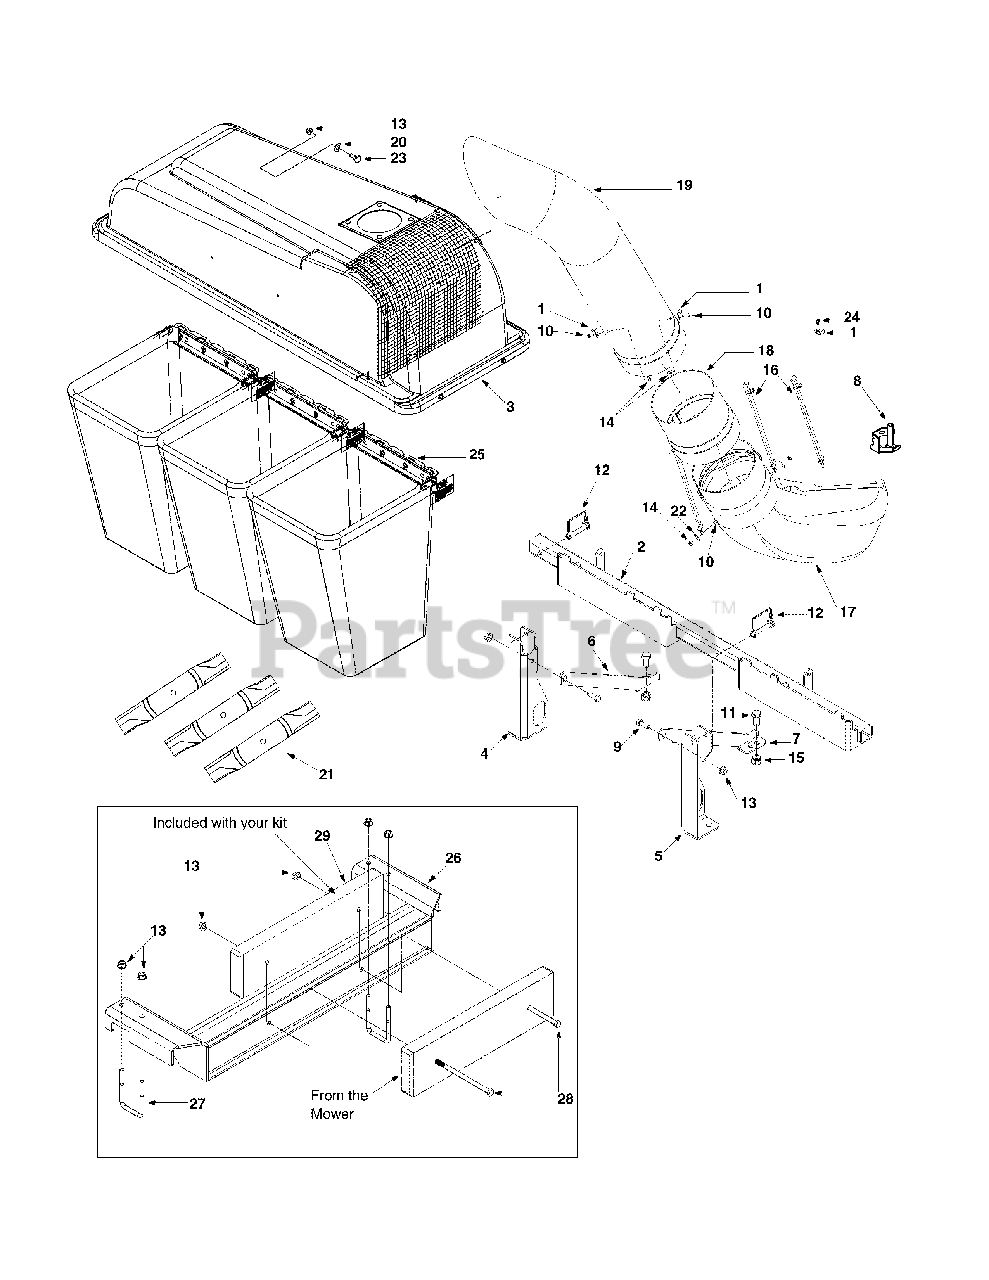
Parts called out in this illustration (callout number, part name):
1	Retainer Hook
2	Catcher Support Bracket
3	Catcher Cover (see assembly)
4	Upright Mounting Bracket LH
5	Upright Mounting Bracket RH
6	Upright Gusset LH
7	Upright Gusset RH
9	Hex Bolt 3/8-16 x 1.0"
10	Hex Bolt 1/4-20 x 0.620"
11	Hex Bolt 1/2-13 x 1.0"
13	Top Lock Flange Nut 3/8-16
14	Flange Lock Nut 1/4-20
15	Lock Nut 1/2-13
16	Chute Strap
17	Chute Elbow
18	Extension Tube
19	Chute Tube
20	Belleville Washer
22	Flat Washer
23	Shoulder Screw 3/8-16
24	Hex Screw 1/4-20
25	Grass Bag
26	Weight Bar Bracket
27	U Bolt 3/8-16 x 1.5"
28	Hex Bolt 3/8-16 x 6.25"
